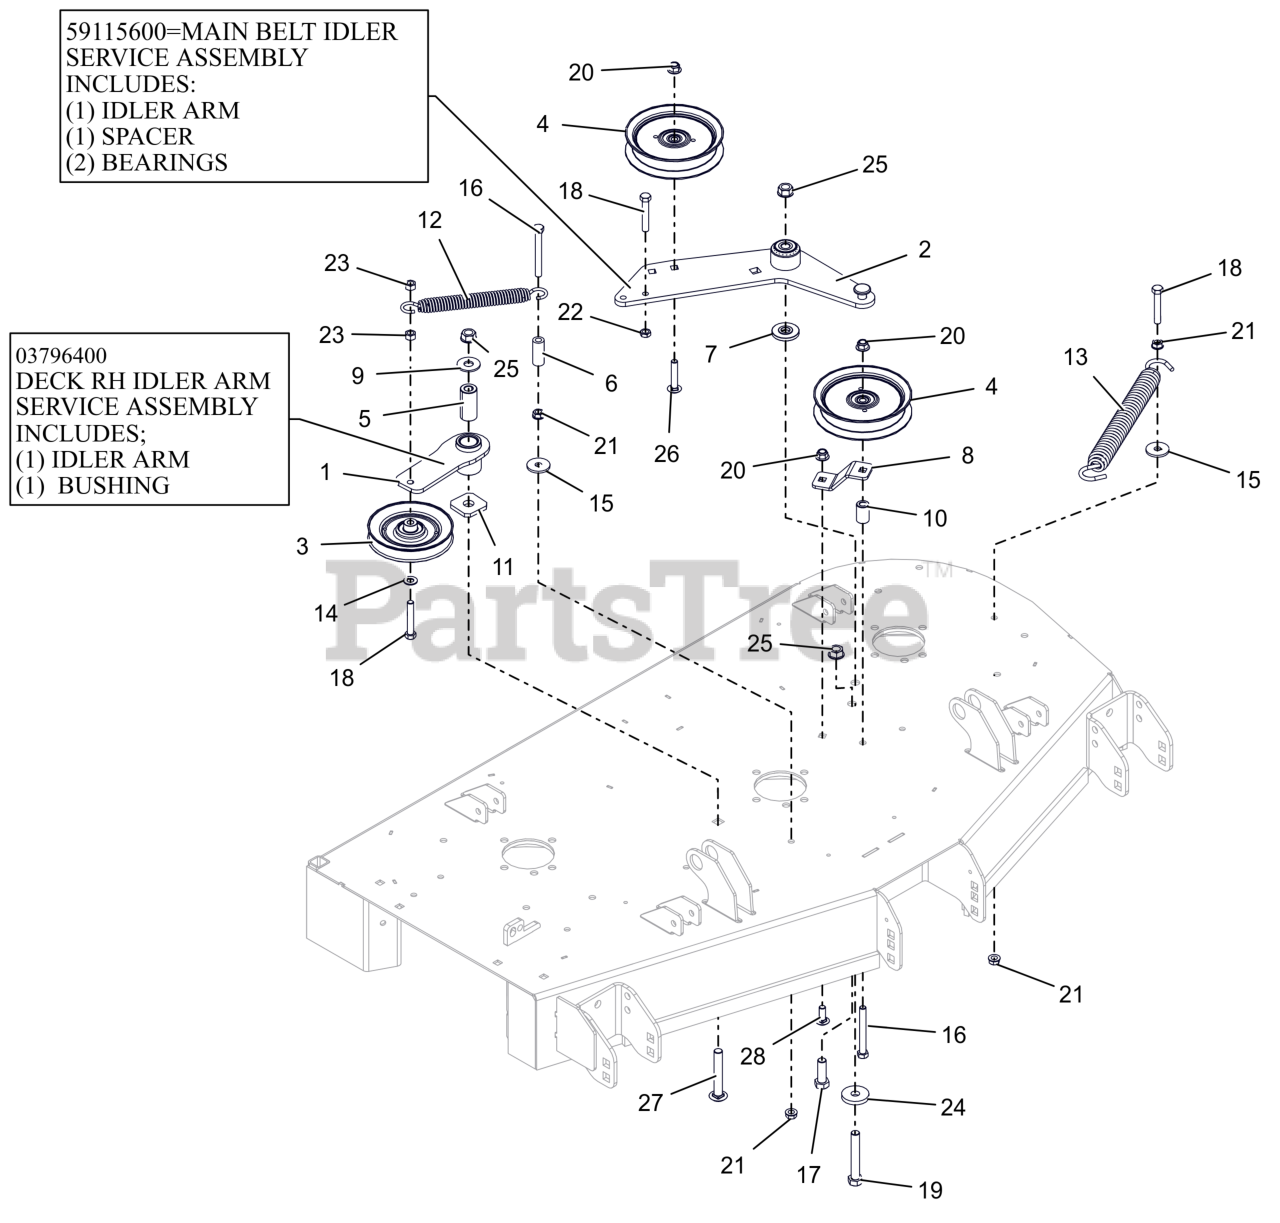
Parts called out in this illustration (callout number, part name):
1	WMT, IDLER ARM - BLACK
2	WLDMT, DECK PTO IDLR ARM
3	IDLER, V-5.00"
4	IDLER, FLAT 5.00"
5	BSHG, SPCR .502X.997X2.03 PM
6	HOSE, .38 X 1.65
7	SPACER, IDLER ARM
8	PTO FIXED IDLER MTG BRKT-ORG
9	WSHR,FLT .563X1.375X.109 ZCC
10	BUSHING, SLV .380X.750X1.190
11	WSHR-FLT .640X1.75X.250
12	SPRING, EXTENSION
13	SPRING, EXTENSION
14	WSHR,FLT .406X.812X.065 ZCC
15	WSHR,FLT .406X1.375X.135 ZCC
16	BLT, HEX .38-16X3.25 G5 ZCC
17	BLT,HEX .50-13X1.50 G5 ZCC
18	BLT,HEX .38-16X2.25 G5 ZCC
19	BLT,HEX .50-13X3.25 G5 ZCC
20	NUT,NYL-FLG .38-16 GF ZCC
21	NUT, SPNLK-FLG .38-16 G5 ZCC
22	NUT-JAM .375-16 G2 ZCC
23	NUT-LK-CTR .38-16 ZC120
24	WSHR-FL-STL .515X1.625X.250 YZ
25	NUT-LK-CTR-FLG .500-13 GG ZCC
26	BLT,RHSSN.375-16X2.00 G5 ZCC
27	BTL,RHSSN .500-13 X 3.25 G5 ZCC
28	BLT,RHSSN .38-16X1.00 G5 ZCC
